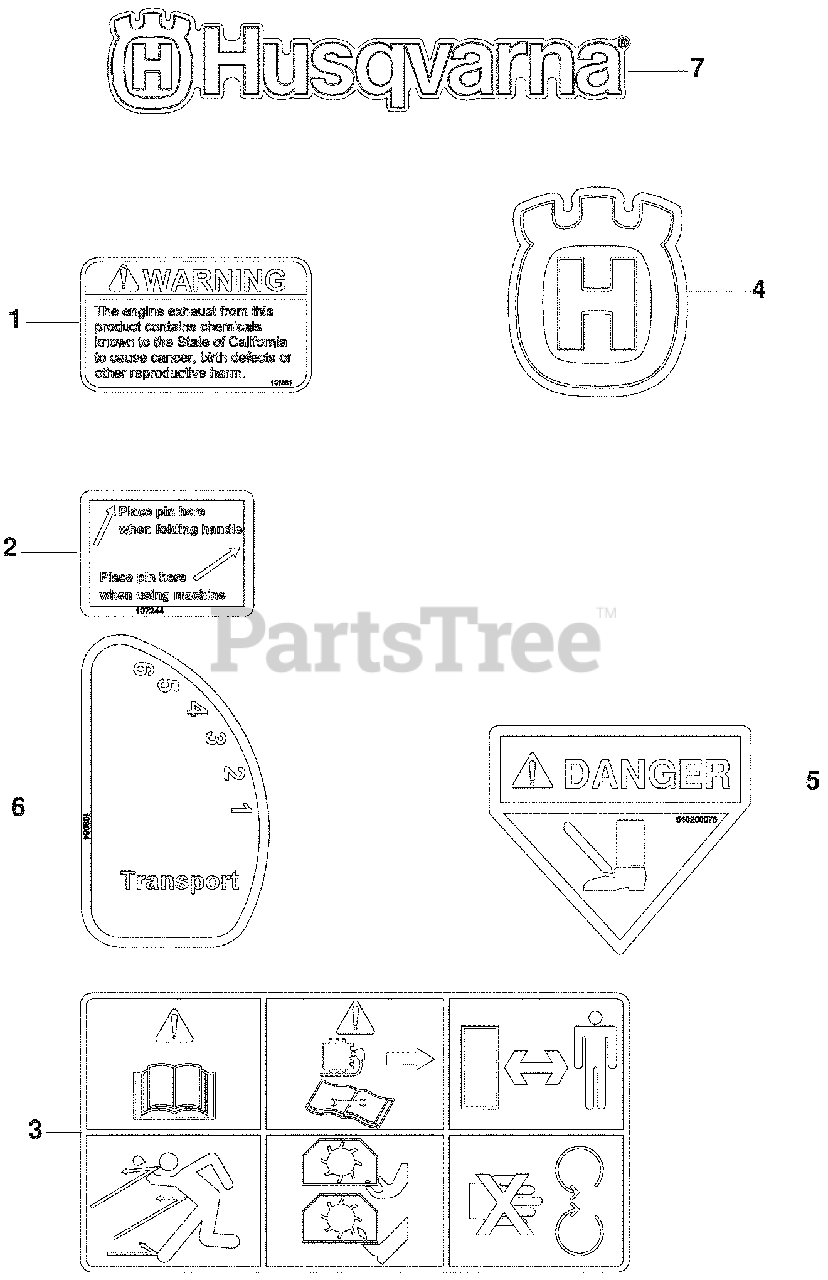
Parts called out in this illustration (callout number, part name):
1	DECAL, PROP 65
2	DECAL, HANDLE PIN
3	DECAL, SAFETY GRAPHICS
4	DECAL, CROWN
5	DECAL, DANGER FOOT
6	DECAL, DEPTH
7	DECAL, HUSQVARNA
